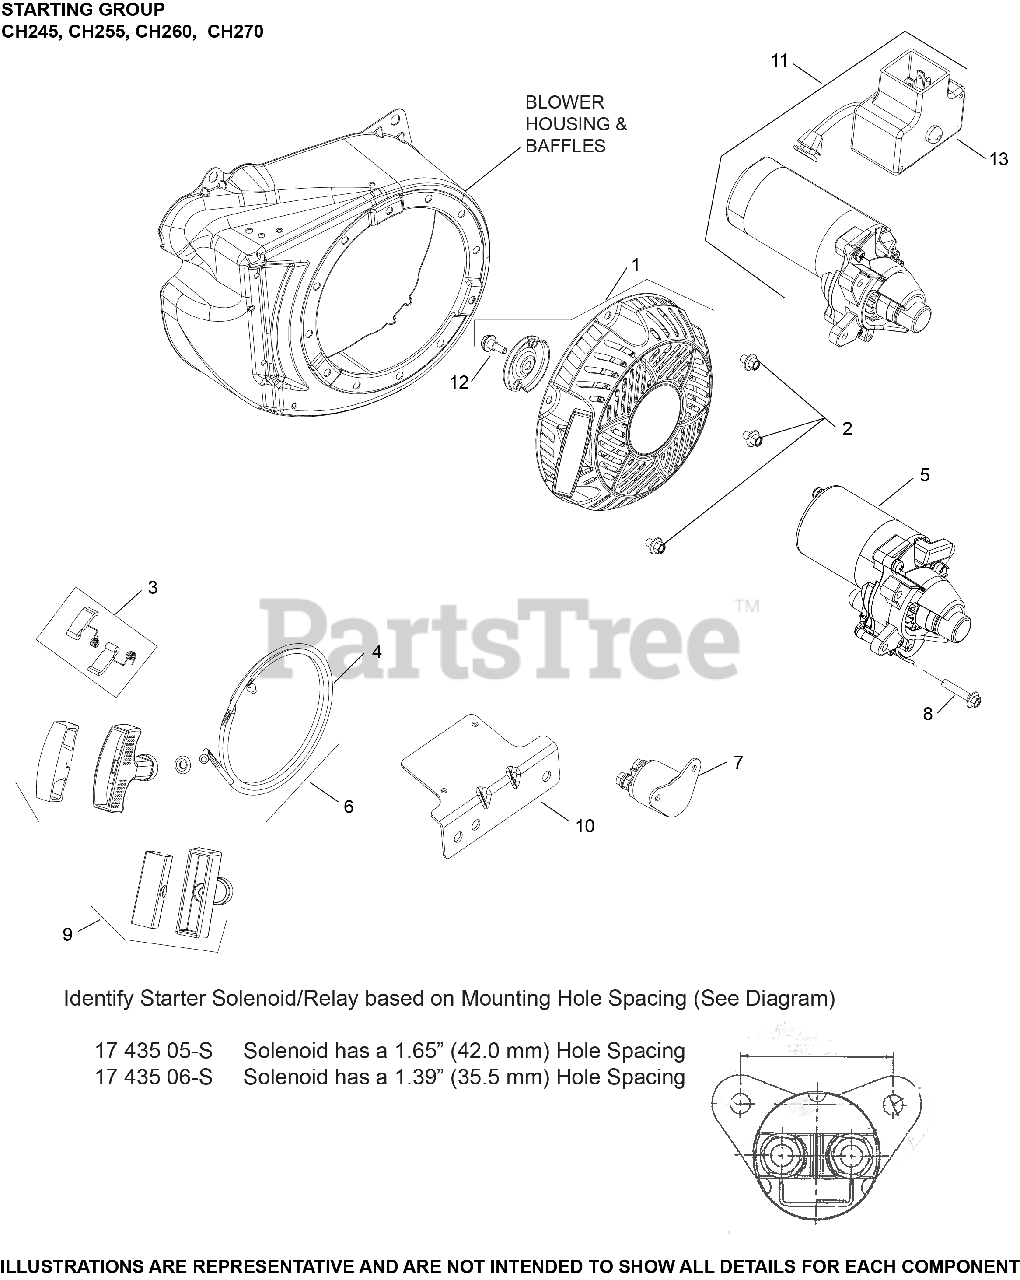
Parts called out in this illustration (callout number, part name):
1	RETRACTABLE STARTER ASSEMBLY
2	SCREW, M6 X 8 HEX FLANGE HEAD (CKY)
4	ROPE, STARTING
9	KIT, HANDLE
